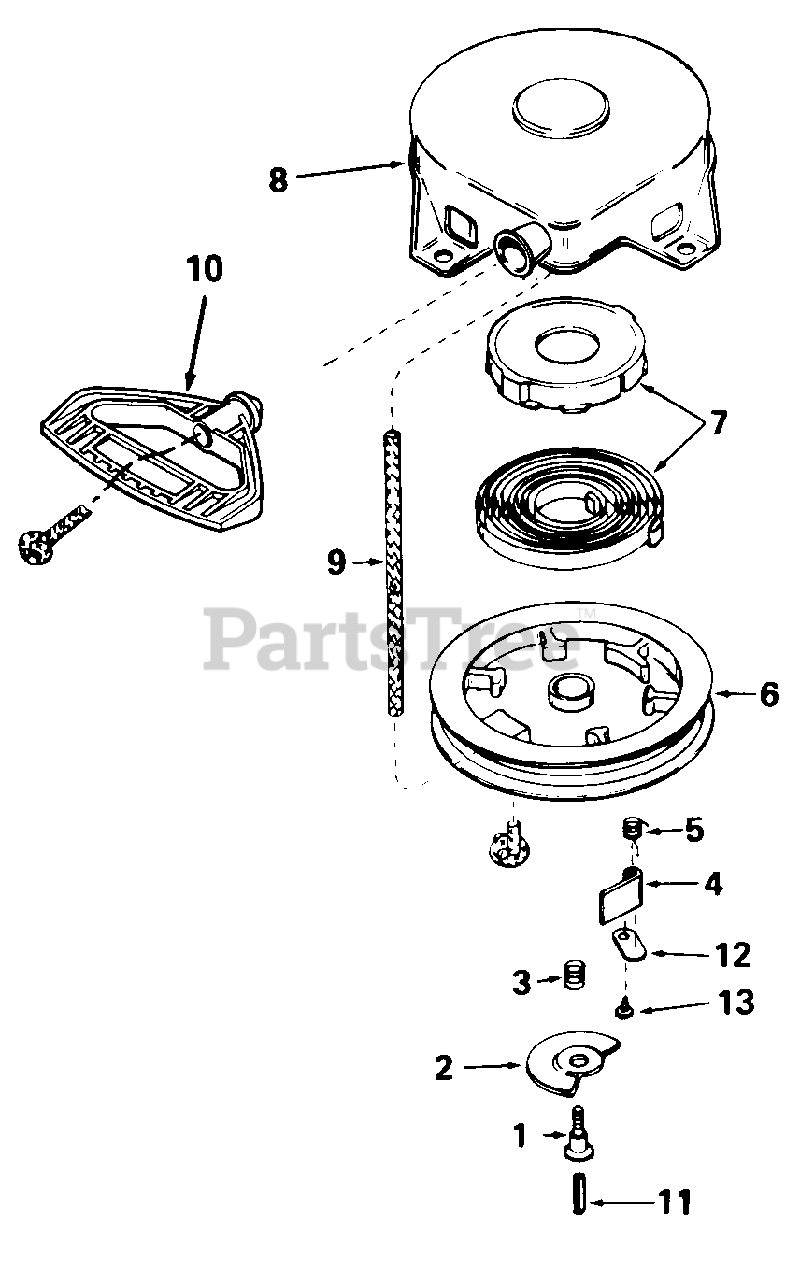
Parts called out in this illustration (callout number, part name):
1	Screw, Retainer
3	Spring, Brake
4	Dog, Starter
5	Spring, Dog
7	Spring & Keeper Ass'y.
8	Housing Ass'y., Starter
9	Rope, Starter
10	Handle, Mitten Grip
11	Pin, Centering
12	Retainer, Dog
13	Screw, No. 6 x 5/16
